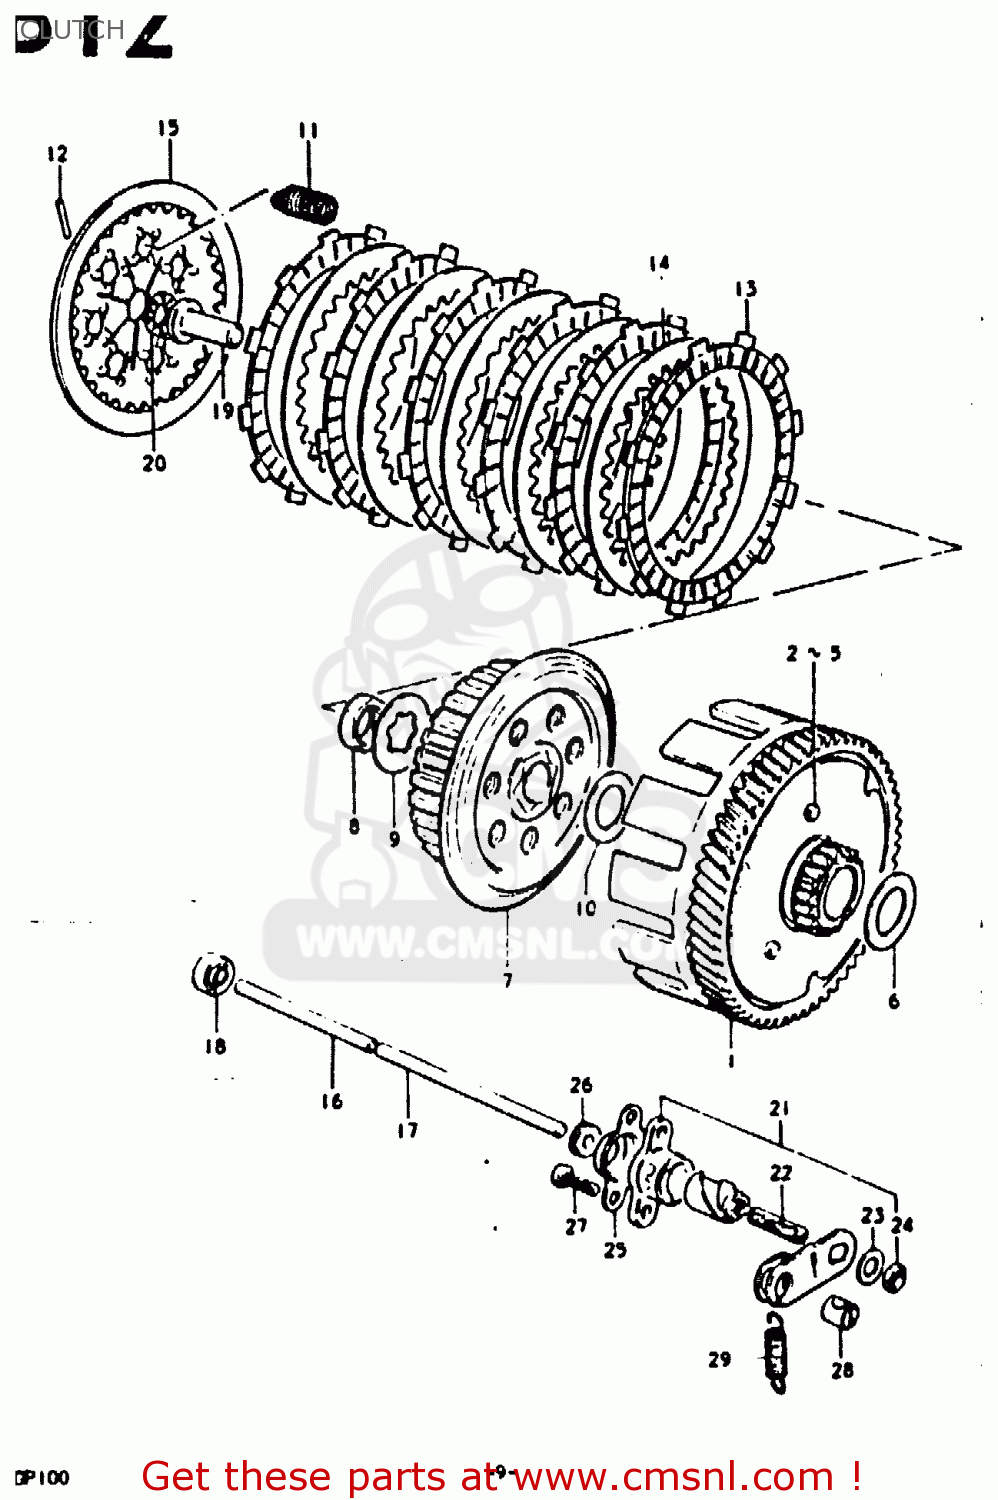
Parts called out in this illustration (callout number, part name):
1	GEAR ASSY, PRIMARY DRIVEN
2	DAMPER,PRIMARY DRIVEN
3	DAMPER,PRI DRIVEN GEAR NO.2
4	PLATE
5	RIVET
6	WASHER
7	HUB,CLUTCH SLEEVE
8	NUT
9	WASHER,LOCK
10	WASHER
11	SPRING
12	PIN(2.5X19.8)
13	PLATE,CLUTCH DRIVE
14	PLATE,CLUTCH DRIVEN (NAS)
15	PLATE,CLUTCH PRESSURE
16	ROD,CLUTCH PUSH
17	ROD,CLUTCH PUSH
18	OIL SEAL
19	PIECE, PUSH
20	BEARING(10X22X2.8)
21	SCREW ASSY, RELEASE
22	SCREW
23	WASHER(6.5X16X1.2)
24	NUT 6MM
25	COVER,CLUTCH RELEASE SCREW
26	SEAL,DUST(5.3X13X5)
27	SCREW
28	PIECE,RELEASE ARM END
29	SPRING
